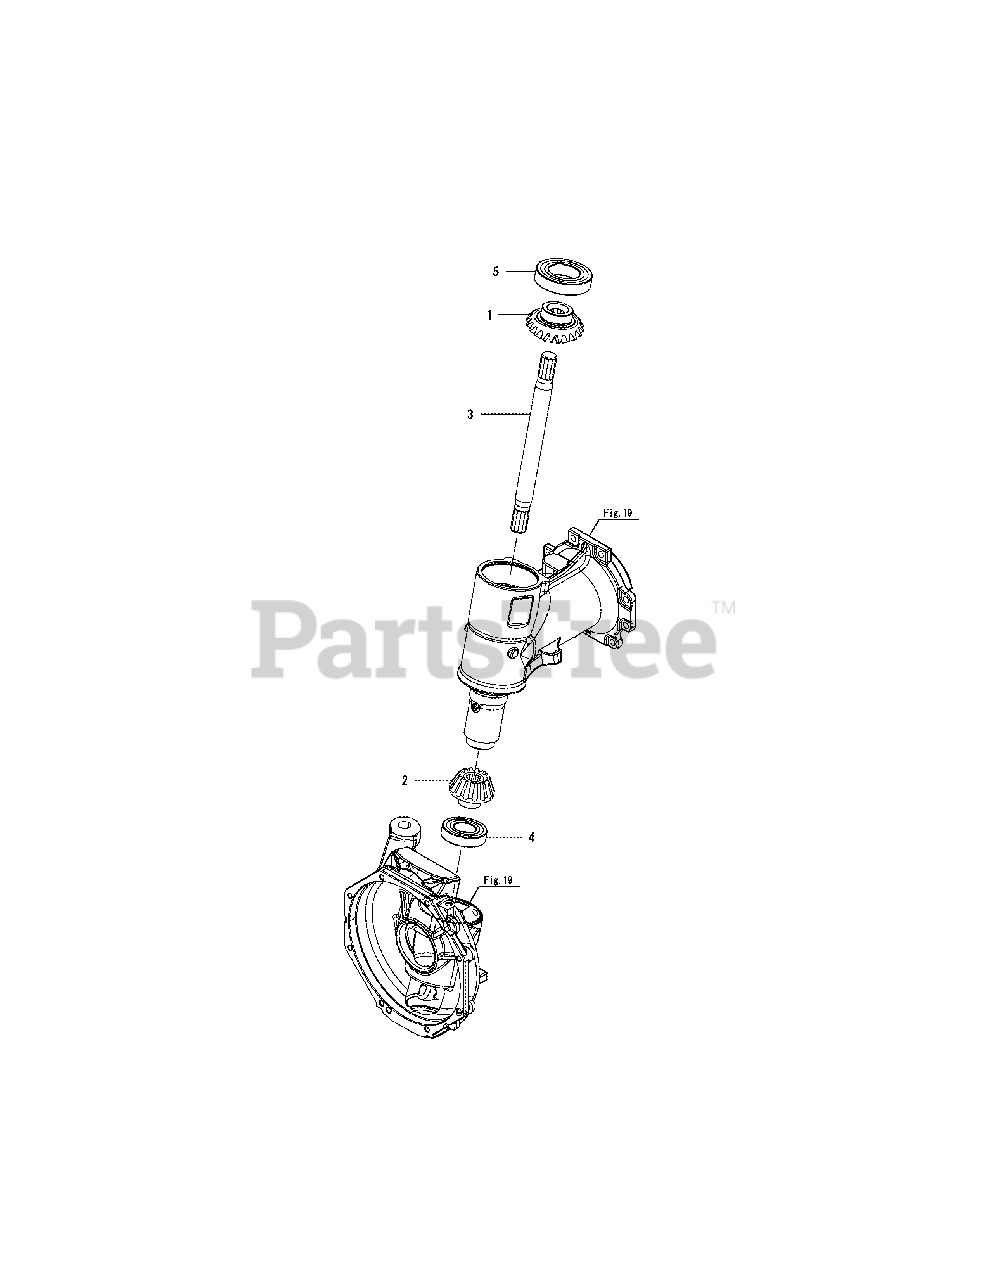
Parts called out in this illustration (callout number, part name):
1	GEAR, 2ND SHAFT 15
2	PINION, FAINAL 11
3	SHAFT, FRONT 2ND
4	BEARING, TM207UR
